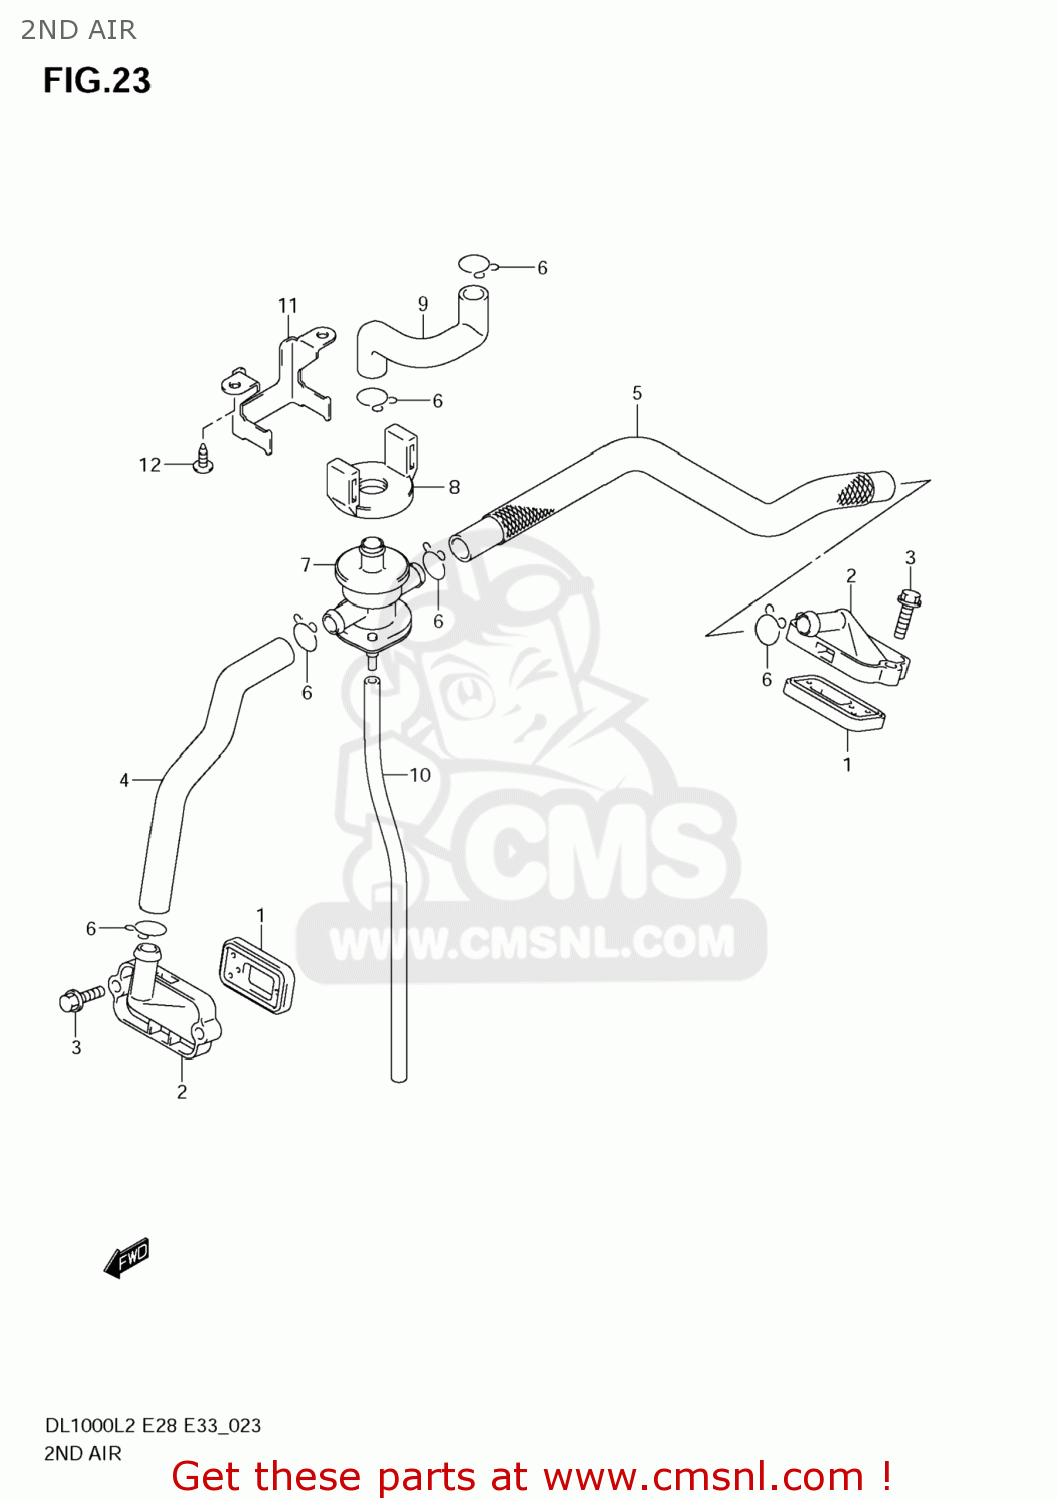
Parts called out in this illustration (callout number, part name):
1	VALVE ASSY,2ND AIR REED
2	COVER,2ND AIR
3	BOLT(6X20)
4	HOSE,2ND AIR VALVE FR
5	HOSE,2ND AIR VALVE RR
6	CLIP
7	VALVE ASSY,AIR CUT
8	CUSHION,2ND AIR VALVE
9	HOSE,2ND AIR CLEANER
10	HOSE,AIR VALVE NO.2
11	BRACKET,2ND AIR VALVE
12	SCREW
